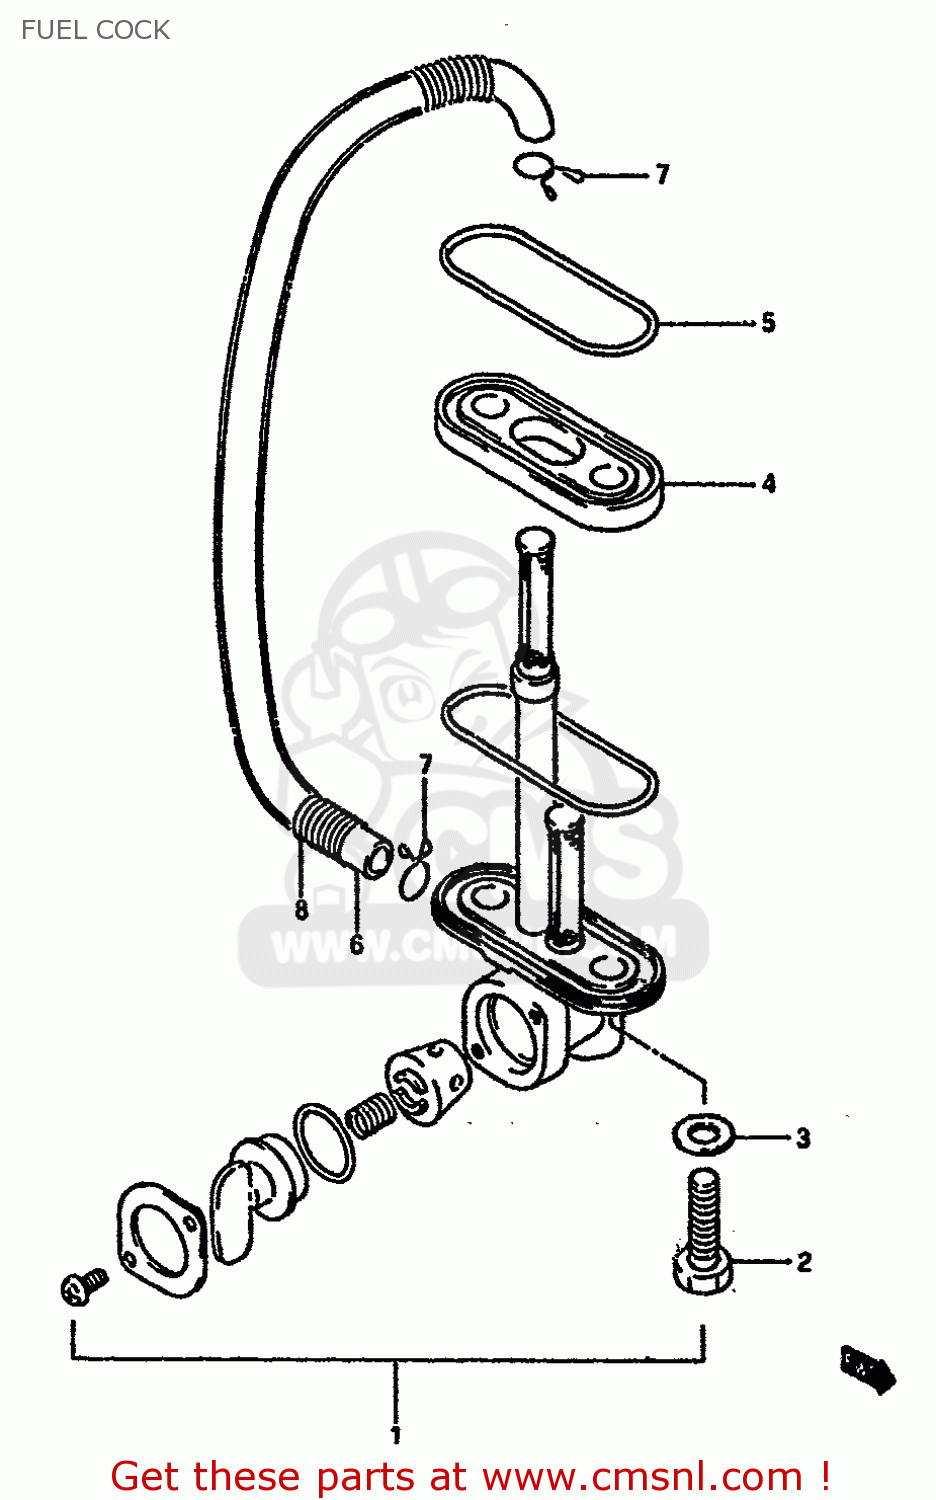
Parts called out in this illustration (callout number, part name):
1	COCK ASSY,FUEL
2	BOLT(6X20)
3	GASKET
4	SPACER,FUEL COCK
5	GASKET,FUEL COCK (NAS)
6	HOSE
7	CLIP
8	SPRING
